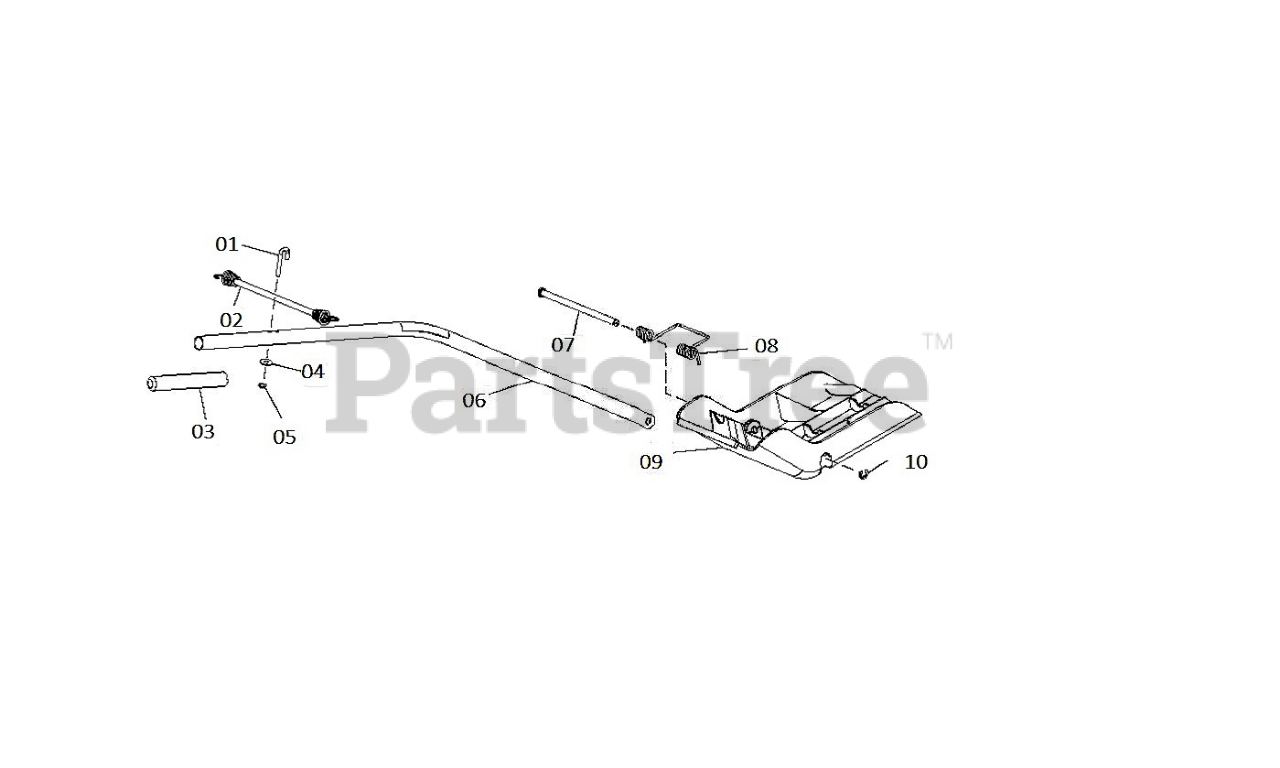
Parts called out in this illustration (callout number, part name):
01	BOLT BOLT J
02	BUBGEE BUBGEE TEX CRD
03	GRIP GRIP MULCH PLUG HAND
06	SHAFT SHAFT TEX CRD MULCH PLU
07	PIN PIN.HINGE
08	SPRING SPRING DOUBLE TORSION
09	PLUG PLUG
10	E-RING.5/16"
